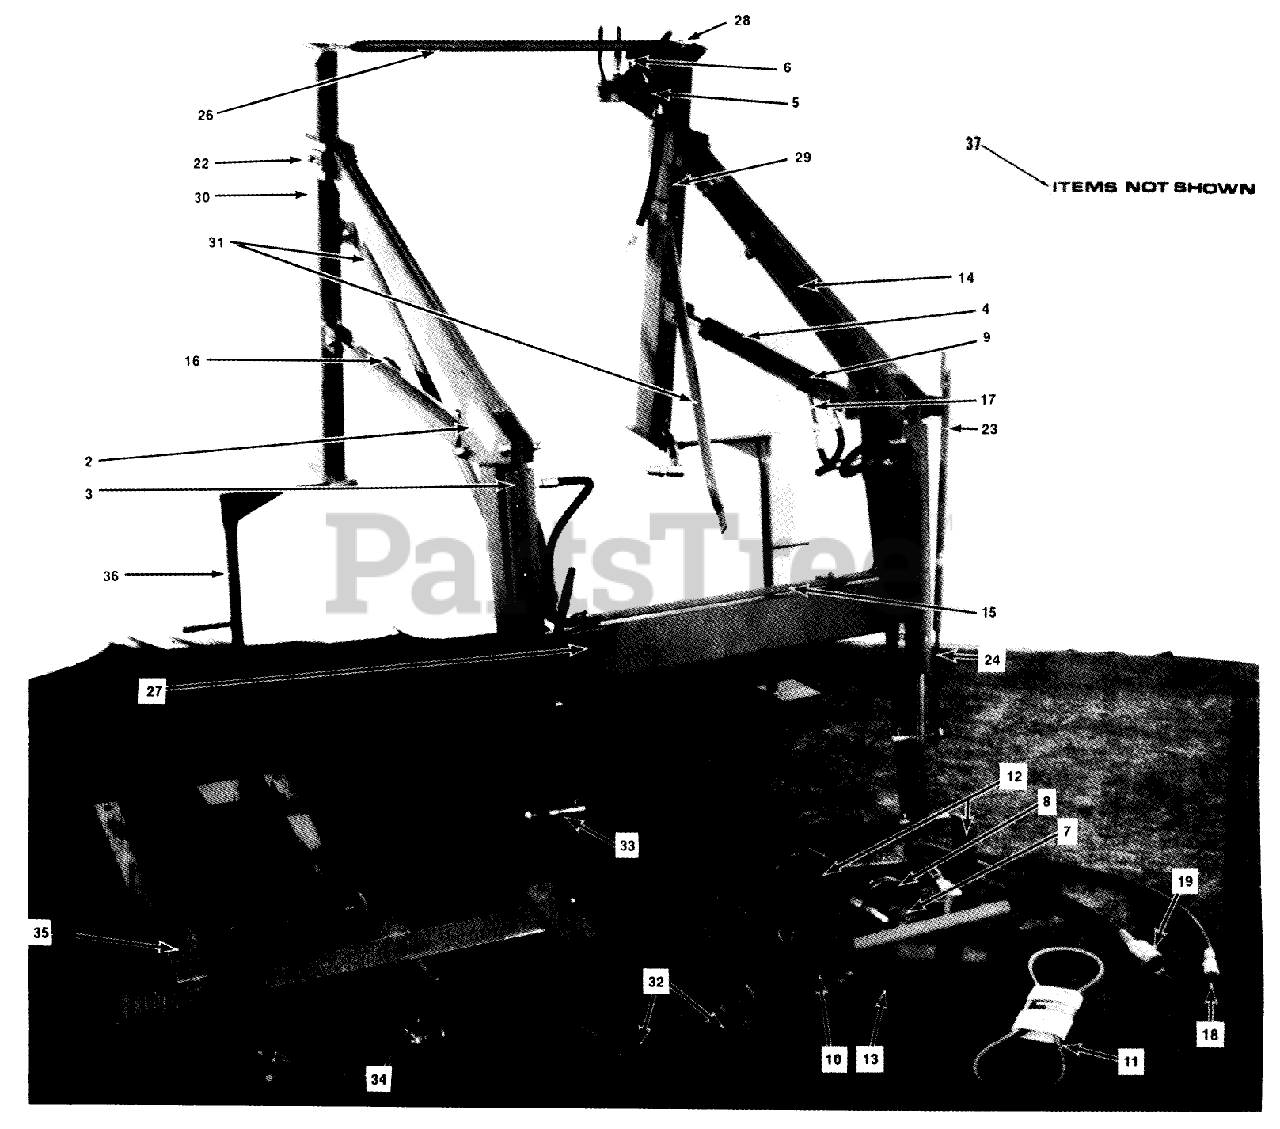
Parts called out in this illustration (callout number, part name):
2	Decal, Wheel Horse
3	Tilt Cylinder
4	Lift Cylinder
5	Control VaIve
6	Valve Handle (with Cover)
6	Black Vinyl Cover
7	Retainer-Spring
8	Pulley
9	52014/15/90A RER 34
10	Pump Mounting Plate
11	1402A GIL DOZER BLA
12	Pump Mounting Bracket LH
12	Pump Mounting Bracket RH
13	Pump Guard
14	Hydraulic Line
15	Hydraulic Line
16	Hydraulic Cylinder Tube LH
17	Hydraulic Cylinder Tube RH
18	Quick Coupler 3/8 (Pressure Hose)
19	Quick Coupler 1/2 (Suction Hose)
22	Lift Frame Pin
23	Bucket Guide Tube
24	Bucket Guide Rod
26	Stabilizer Bar
27	Lift Frame
28	Breather Cap
29	Upright LH
30	Upright Assembly (Right)
31	1840A 1973 OPC
32	Front Mounting Bracket LH
32	Front Mounting Bracket RH
33	Cylinder Spacer/Bushing
34	Mounting Frame Hanger LH
34	Mounting Frame Hanger RH
35	Mounting Frame
36	Dismount Stand
37	Caution Decal
37	Hydraulic Line Bracket
37	Hydraulic Line Hold Down
37	Grease Fitting
37	Bushing (Guide Rod)
37	Bucket 48 in. (122 cm)
37	Ballast Box w/Brackets Braces
37	Ballast Box Bracket
37	Ballast Box Brace
